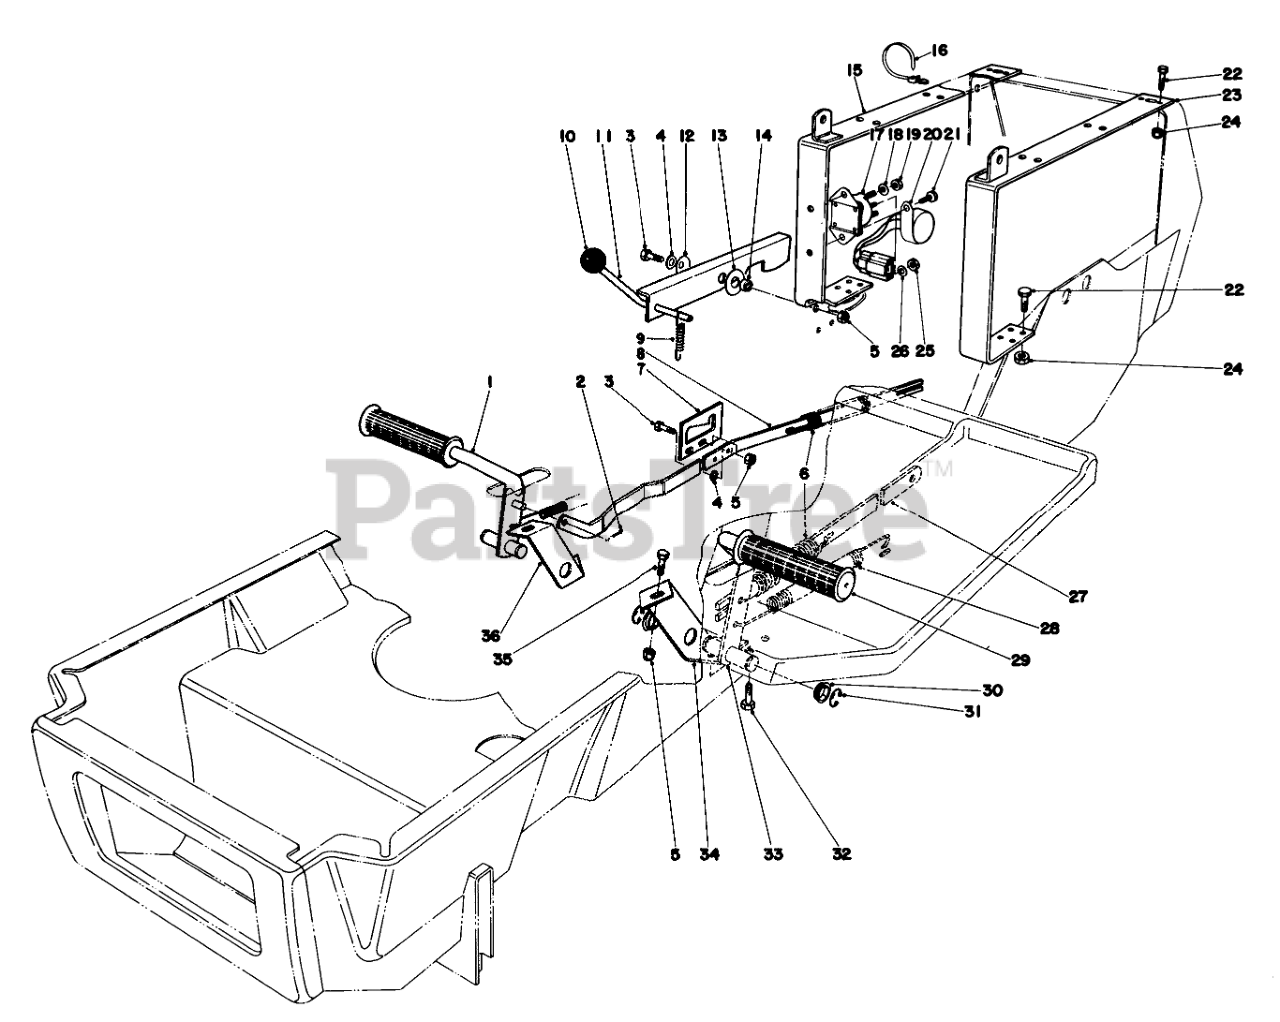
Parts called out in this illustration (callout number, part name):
1	BRAKE PEDAL WA BO
2	PIN-COTTER
3	SCREW-HH
4	WASHER-PLAIN
5	NUT-LOCK, CONE
6	EXT SPRING O
7	LATCH PLT-BRAKE ROD
8	LINK BRAKE ROD WAB
9	CONT ROD SPRING 0
11	PARKING BRAKE WA B
12	Belleville Washer
13	WASHER-PLASTIC
14	SPACER
15	RR BODY STRAP WA B
16	Push Mount Tie
17	SOLENOID
18	Lockwasher
19	NUT-JAM, BRASS
20	Module Interlock
21	SCREW-HWH
22	SCREW-HH
23	LH RR BODY STRAP WA B
25	NUT-HEX
26	WASHER-LOCK
27	CLUTCH ROD LINK B
28	SPRING-EXTENSION
29	FOOT PAD
30	Nyliner
31	E-RING
32	SCREW-HWHTF
33	CLUTCH PEDAL WA BO
34	LH PEDAL SUPT B
35	SCREW-HH
36	RH PEDAL SUPT B
